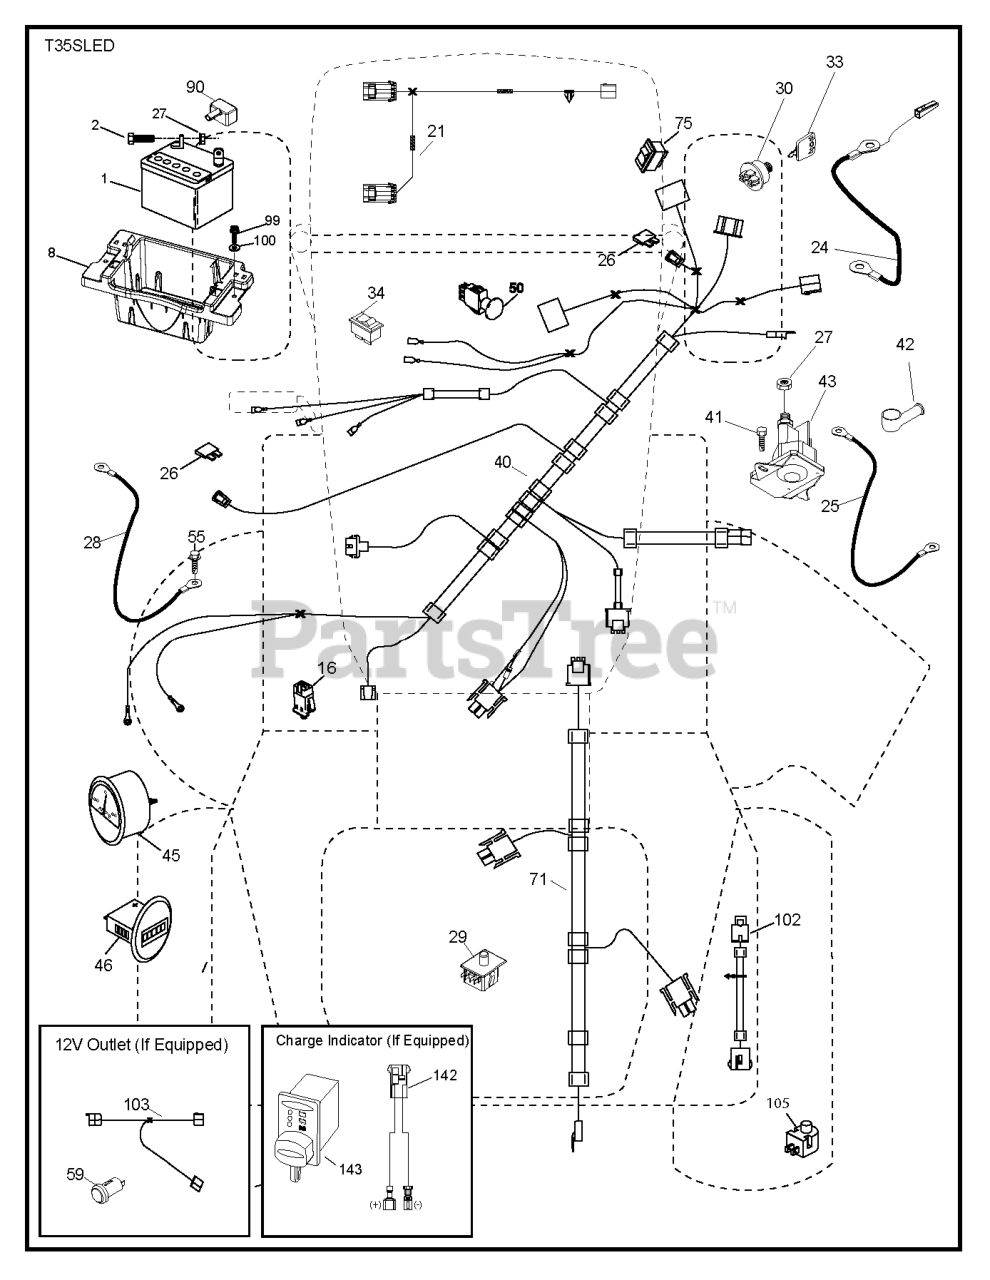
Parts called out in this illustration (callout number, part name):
1	Battery 12 Volt 25 Amp
2	BOLT.HEX.1/4.X.3/4.DICHROMATE
8	TRAY.BATTERY BOX.FRONT
16	SWITCH INTERLOOK PUSH-IN
21	HARNESS LIGHT ASSY TRACTOR,
24	CABLE.FRBATT.W/WIRE.8GA.8
25	CABLE.STARTER.8GA.17.5
26	FUSE 20AMP
27	NUT
28	CABLE.GROUND.21"BLK.8GA.90T
29	SWITCH.SEAT.DP W/RAMPS
30	SWITCH.IGN.DELTA.W.LGH.ROS
33	KEY.CHAIN.BLISTER.PACK.GEN.USA
41	SCREW
42	TERMINAL COVER
43	SOLENOID.STARTER.BRASS.PLUNGER
45	GAUGE.AMMETER.SILVER/WHITE
46	GAUGE.HOUR.METER.SILVER/WHITE
50	SWITCH.PTO.8TERMINAL.STD.BLK
55	SCREW 5/16"
71	HARNESS.IGN.CHASSIS.TEX.DCKLOC
75	SWITCH.ON/OFF.(DIFF.LOCK)
90	COVER.TERMINAL.BATTERY
99	SCREW HEXWSHR 1/4-20X3/4
100	WASHER
102	HARNESS PIGTAIL PCH TEX ROS
105	REVERSE SWITCH
143	CHARGE.PORT
